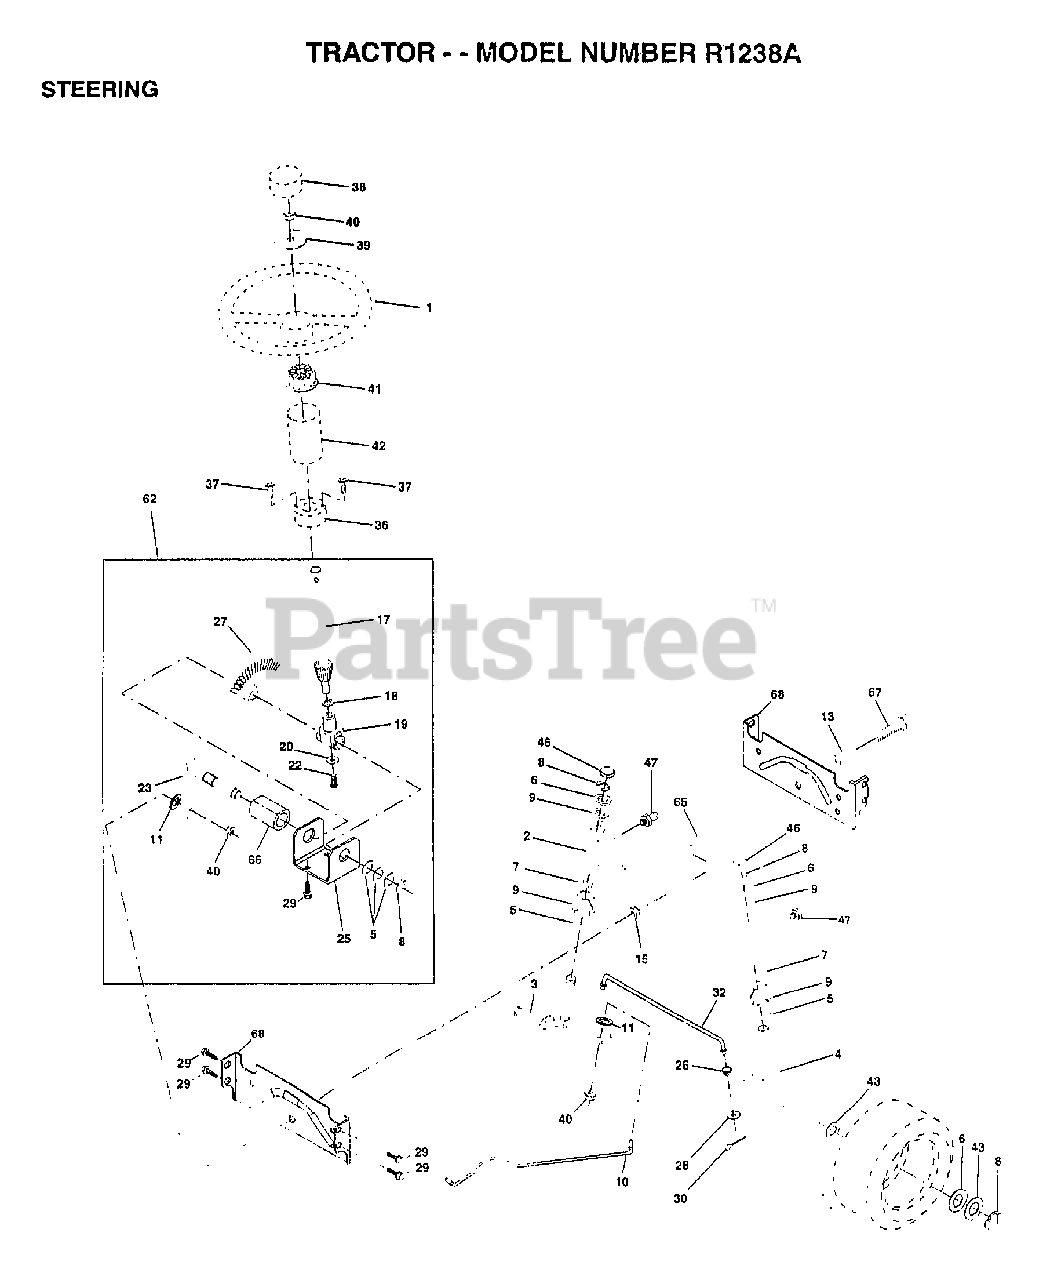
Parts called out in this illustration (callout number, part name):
2	AXLE ASM
3	SPINDLE.ASM.LH
4	"SPINDLE ASM,RH"
5	WASHER .T
6	WASHER
7	WASHER
8	RING
9	COL. SRTG. BEAR.
10	DRAGLINK-STAMPED
11	LOCKWASHER
13	BEARING AXLE
15	"NUT-LOC,FLANGE LT"
17	SHAFT ASSM STEERN
18	THRUST WASHER
19	SUPPORT.SHAFT
22	SCREW HEX SOC1/4-
25	BRKT-STEERING
26	BUSHING.DRAGLINK
27	GEAR SECTOR
28	WASHER
29	SCREW
30	COTTER PIN
32	TIE ROD
36	BUSHING.STEERING
37	"SCREW-TT,10-32 FL"
38	ST WHL INSERT CAP
39	WASHER T
40	GRIPCO NUT
41	ADAPTER-WHEEL LT
42	"TUBE, STR SHAFT"
43	WASHER
46	CAP
47	ZERK M
62	STEERING ASM KIT
65	SPACER AXLE
66	"BEARING-ARM,PITMA"
67	BOLT
68	BRACE AXLE
